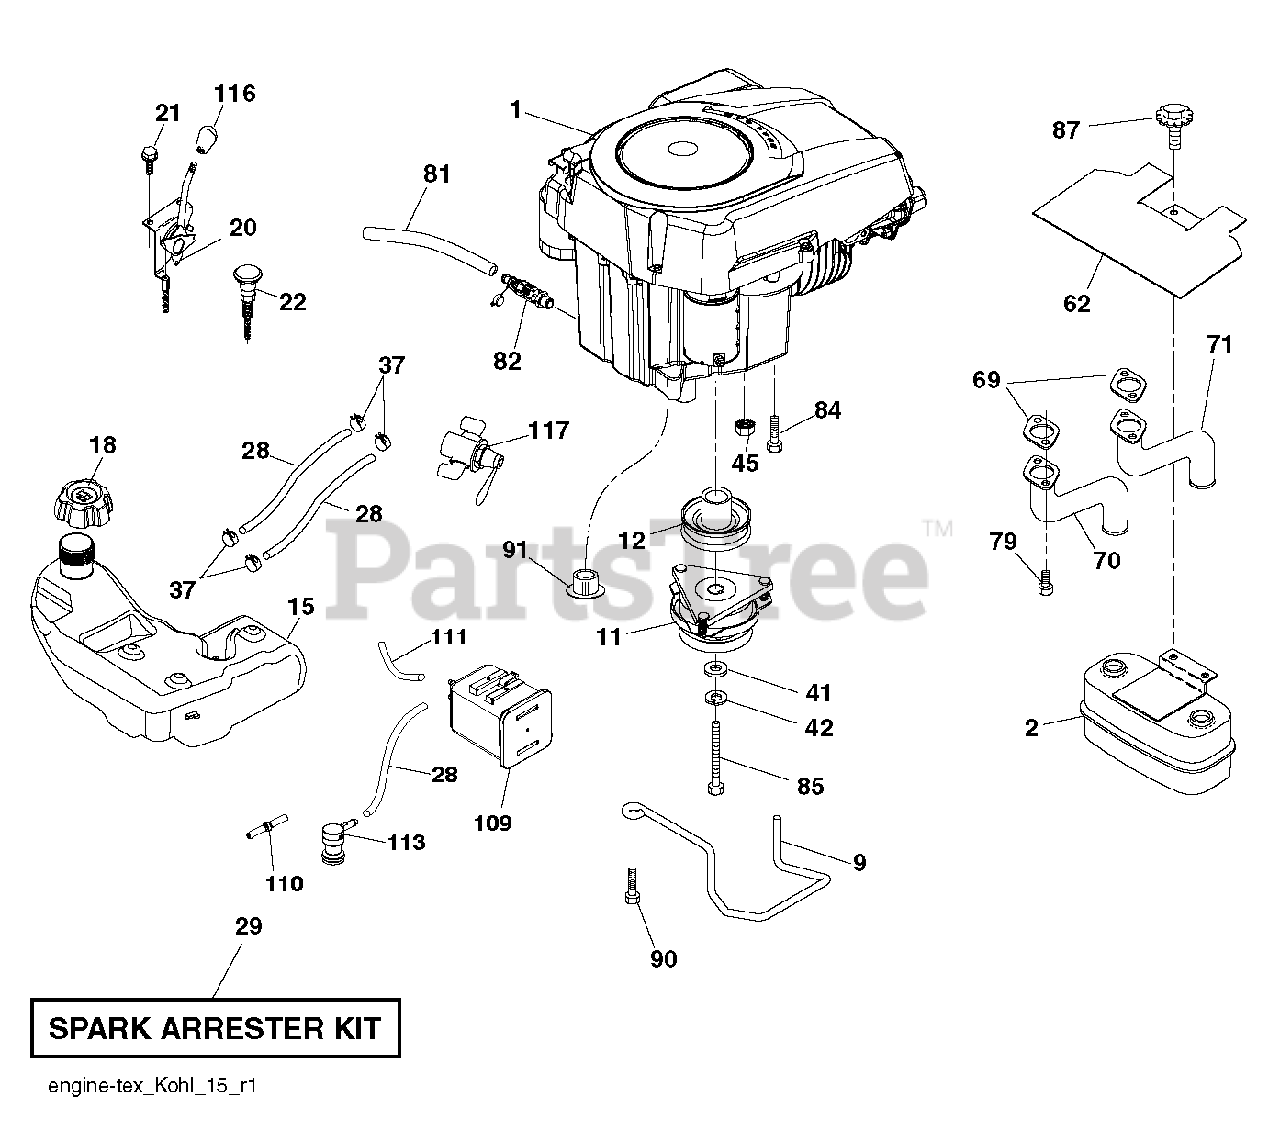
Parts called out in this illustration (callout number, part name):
2	MUFFLER.ASM.TWN.EXTNDED.DFLCTR
9	KEEPER BELT ENGINE
11	CLUTCH.OGURA.5.0PD.GT1.5A-EH01
12	PULLEY ENGINE
15	PULLEY ENGINE
18	RP CAP FUEL
20	CONTROL.THROTTLE.PRO.
21	SCREW.#10 X 0.750.BOS
22	CONTROL.CHOKE.ERGO.PUSH-IN.BLA
28	LINE.FUEL.64"REAR.EMIS
29	KIT.SPARK ARRESTOR 794945 B&S
37	HOSE CLAMP
42	LOCKWASHER
45	NUT
62	SHIELD.HEAT.MUFFLER
70	TUBE.EXHAUST.LH.FR961/FR730
71	TUBE.EXHAUST.RH.FR961/FR730
79	SCREW.SOCKET HD.5/16-1
81	TUBE, DRAIN OIL ASM.
82	VALUE.OIL.DRAIN
84	SCREW 3/8-16X1
85	BOLT.HEX.7/16-20X3.0XGR5
87	BOLT, 5/16-18 X 1 3/4
90	SCREW 3/8-16X1
91	BUSHING.1.375OD
109	CANNISTER, CARBON
110	VALVE.ASM.ANTI-SLOSH
111	RP PURGE LINE
113	VALVE.SLANT.CARTRDG.90 DEG.TEX
116	RP KNOB SOFT TOUCH
117	VALVE FUEL RESERVE
